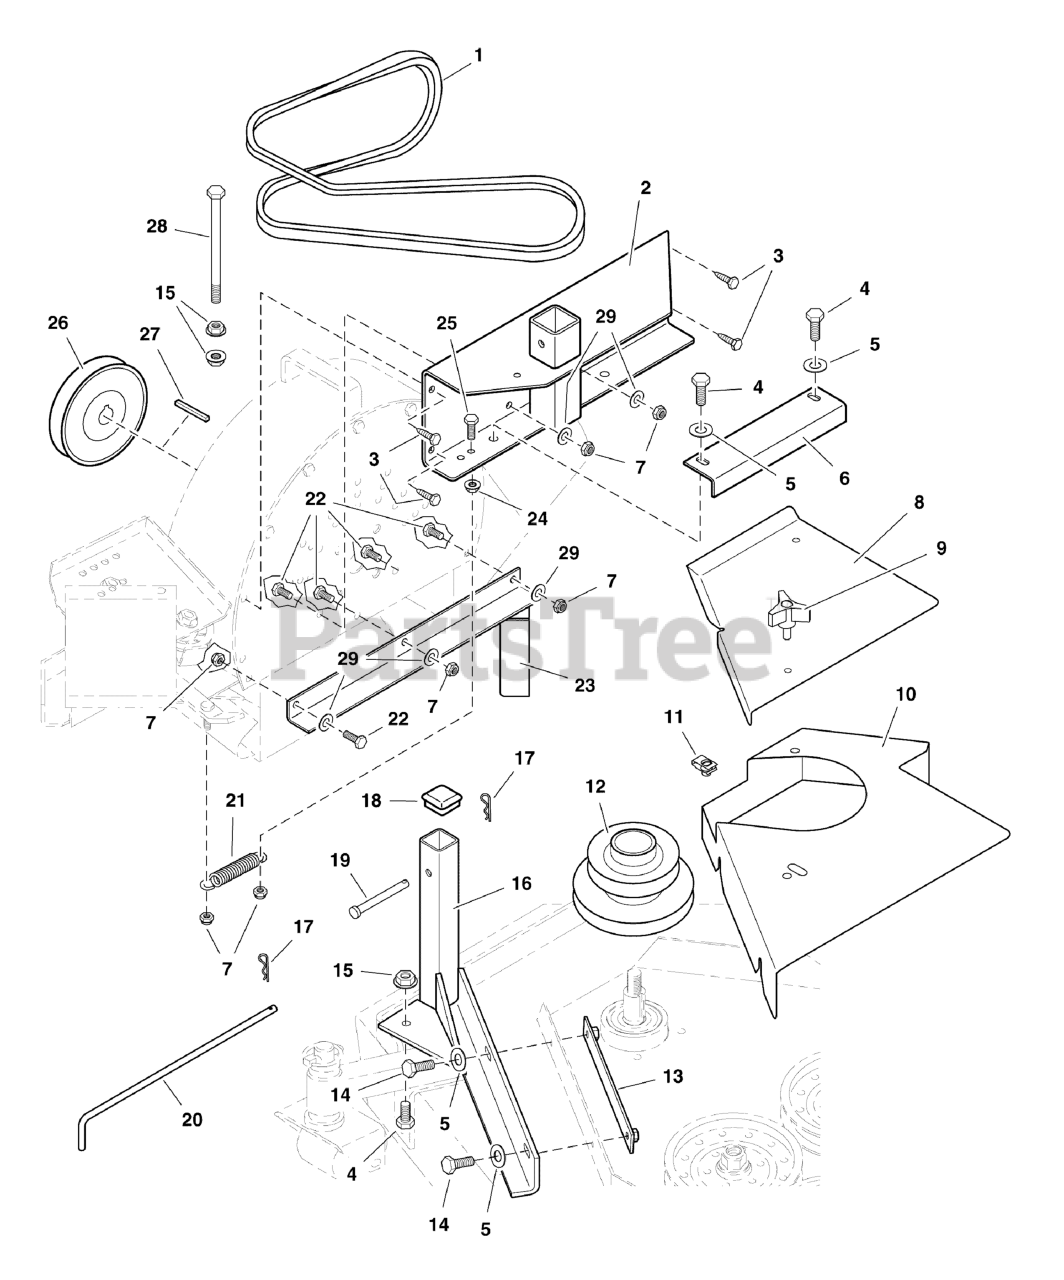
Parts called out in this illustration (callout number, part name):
1	BELT, A-SEC, 92.00EL, ARAMID, WRPD
1	BELT
2	BLOWER MOUNT
3	BOLT, Self-Tapping, 5/16-18 x 3/4
4	BOLT, 3/8-16 X 1" GD5 CZ
5	WASHER, 3/8 SAE
6	BOTTOM BRACE
7	NUT, 5/16-18 Hex Nylon Lock
8	BELT SHIELD
9	KNOB
10	DECK GUARD
11	BODY CLIP, 5/16-18-7GA MATERIAL
12	SPINDLE PULLEY
13	INSIDE SUPPORT
14	BOLT, 3/8-16 X 1-1/4" GD5 CZ
15	NUT, 3/8-16 Hex Serrated Flange
16	BLOWER DECK SUPPORT
17	HAIRPIN CLIP
18	CAP
19	CLEVIS PIN, 3/8 x 4
20	QUICK CONNECT ROD
21	SPRING, Extension
22	BOLT, 5/16-18 X 3/4 GD5
23	BOTTOM ADAPTER
24	NUT, 5/16-18 HEX SERRATED FLANGE (SMALL)
25	BOLT, 5/16-18 x 1-1/4
26	BLOWER DRIVE PULLEY
27	KEY, 1/4 SQ. X 1-1/2
28	BOLT, 3/8-16 X 6" GD5 CZ
29	WASHER, 5/16" SAE
